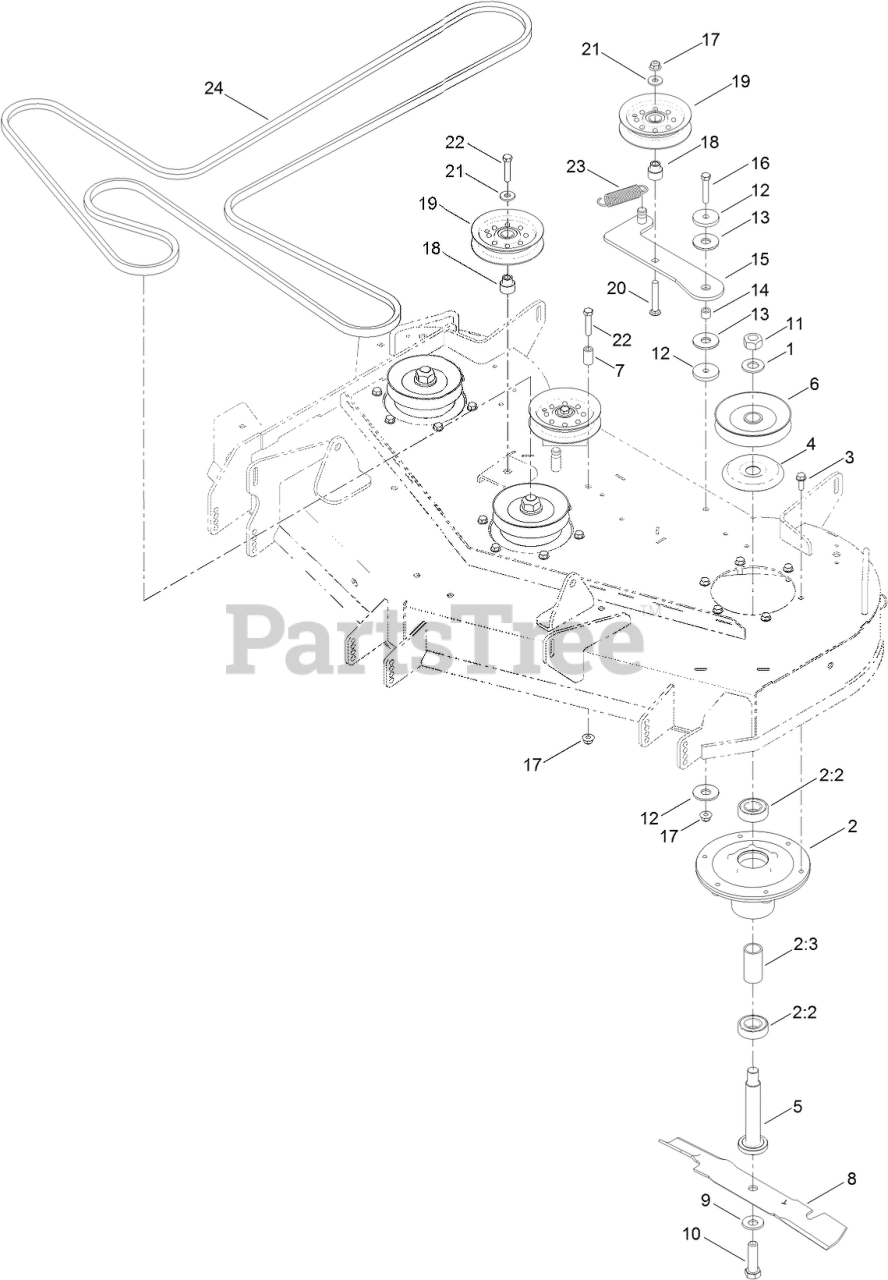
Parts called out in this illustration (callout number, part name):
1	WASHER
2	SPINDLE ASM
2:2	BEARING-BALL
2:3	SPACER-BEARING
3	SCREW-TAPTITE
4	SHIELD-BEARING
5	SHAFT-SPINDLE
6	PULLEY
7	SPACER
8	BLADE-HI FLO, 16.50 INCH
9	WASHER-BELLEVILLE
10	SCREW-BLADE
11	NUT-HEX
12	WASHER-PLAIN
13	WASHER-FRICTION, COMPOSITE
14	BUSHING-LEVER, LIFT
15	ARM-IDLER
16	SCREW-HH
17	NUT-HF, NI
18	BUSHING-IDLER
19	PULLEY-IDLER
20	SCREW-CARR
21	WASHER-HARDENED
22	SCREW-HH
23	SPRING-EXTENSION
24	V-BELT
